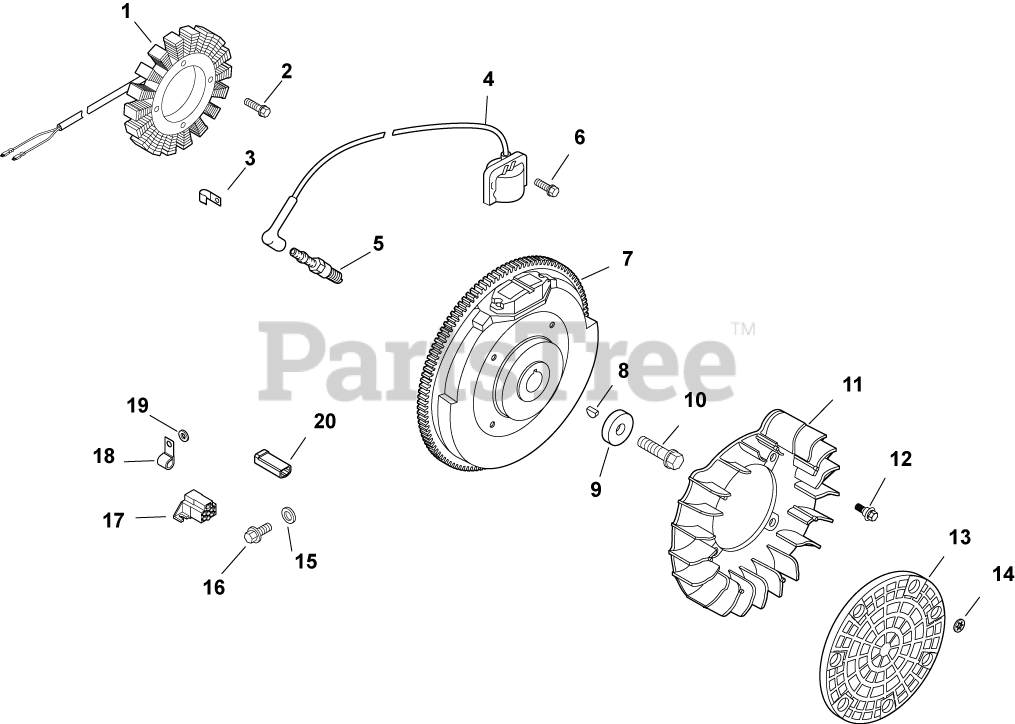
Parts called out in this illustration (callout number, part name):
1	KIT, 15 / 20 AMP STATOR
2	SCREW, M5X0.8X25 - (#25086402S)
3	MODULE, IGNITION-USE 24 584 45-S
6	KEY, 3/16" X 5/8"
7	WASHER, FLAT 13/32"
8	SCREW, FLG M10X1.5X45 - (#25086361S)
9	FAN (KM)-USE 24 157 15-S
10	FAN USE 24 755 253-S
11	BOLT, SHOULDER
13	SCREEN, GRASS
28	SCREEN,GRASS LOW PRFLE W/O HOLE
31	WASHER, FLAT 3/16"
36	SCREW, PHL HD #11-16X7/8"
39	REGULATOR/RECT 12/15A HALF-WAVE STD
42	CONNECTOR
43	CLIP, CABLE
44	WASHER, FLAT 1/4" (O.D. 1/2")
45	CONNECTOR (1 CONTACT)
46	CLIP, TUBE & WIRING (KM)
48	PLUG, SPARK (STD)
54	SWITCH ASSY, KEY (KM)-USE 25 099 32-S
55	WASHER, INTERNAL TOOTH
56	NUT, KEY SWITCH
57	KEY, SET OF 2
59	COVER
67	CONNECTOR
77	TIE
82	LEAD, DUPLEX
83	LEAD, OIL SENTRY
2417676-S	HARNESS, WIRING
2545403-S	TIE, WIRE
24176112-S	HARNESS, WIRING-USE 24 176 150-S
M-561025-S	SCREW, SKT THD FRM M5X0.8X25
